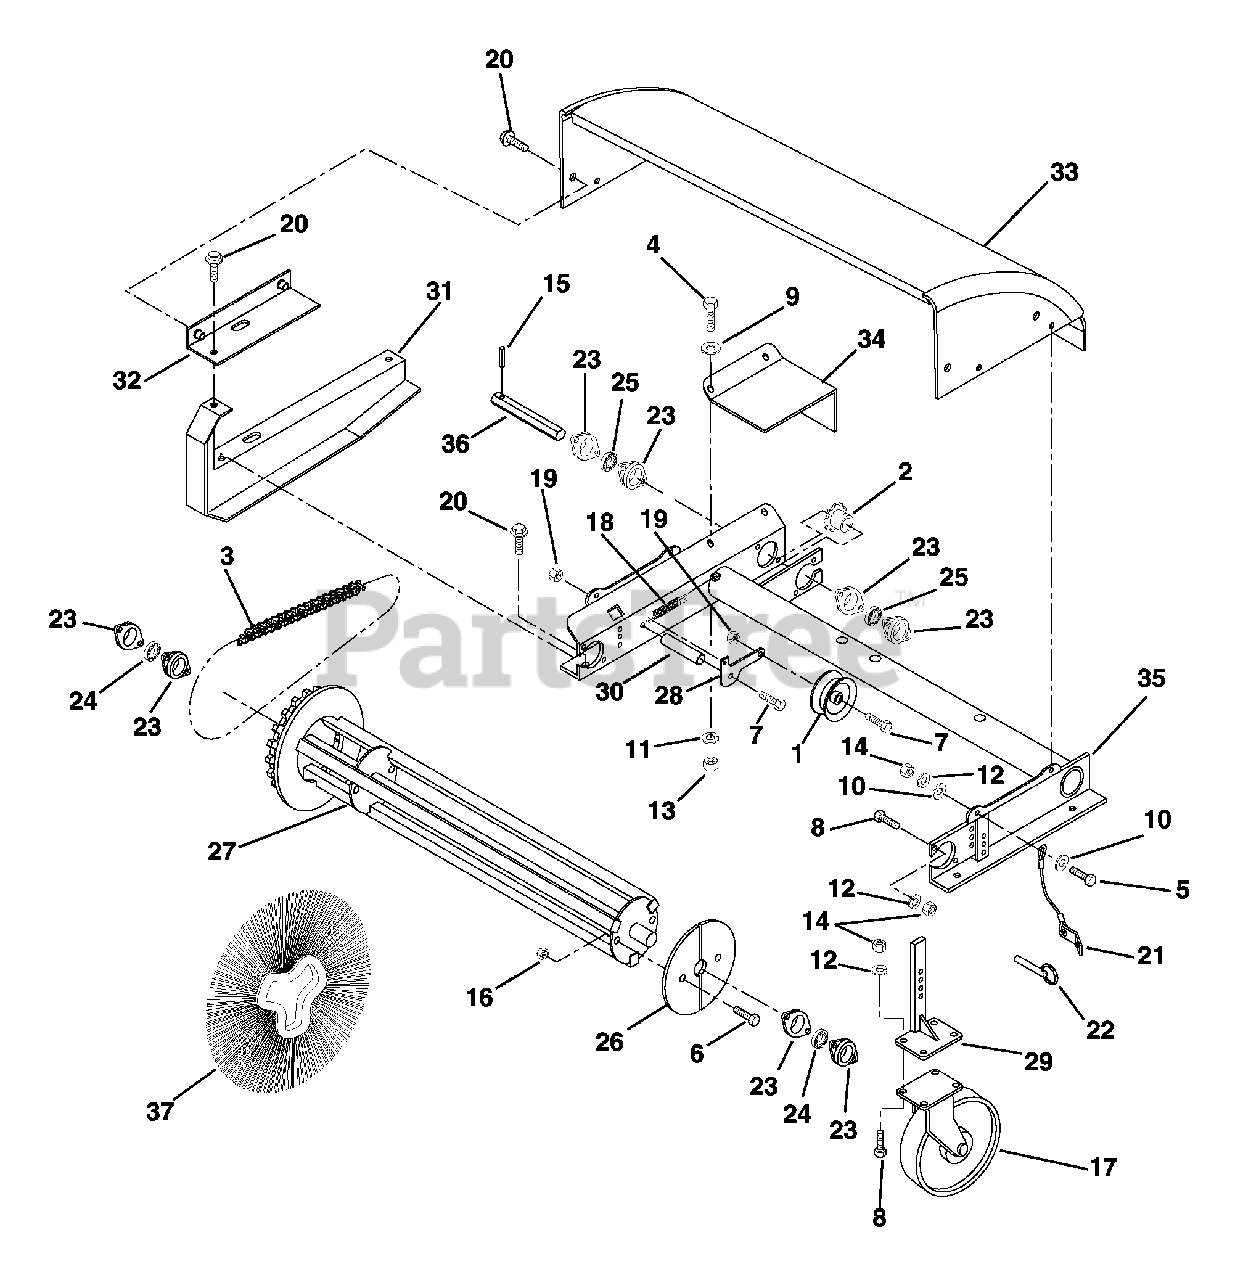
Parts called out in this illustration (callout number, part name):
1	Chain Tightener
2	Sprocket
3	Chain, Assembly #40 x 106
4	Bolt, Hex .25-20 x .75 Grade 5
5	Bolt, Hex .31-18 x 1.00 Grade 5
6	Bolt, Hex .31-18 x 2.25 Grade 5
7	Bolt, Hex .38-16 x 1.50 Grade 5
8	Bolt, Hex .31-18 x .75 Grade 5
9	Washer, Flat Steel .28 x .62 x .065
10	Washer, Flat Steel .31 x .73 x .065
11	Washer, Lock .25 x .062 Regular
12	Washer, Lock .31 x .078 Regular
13	Nut, Hex .25-20
14	Nut, Hex .31-18
15	Pin, Spring Lok .19 x 1.25
16	Nut, Lok Stamped .31-18
17	Wheel, 5 inch Diameter
18	Spring, Tension .50 x 3.00
19	Nut, Locking Center .38-16
20	Screw, Gear 10.9 M6 x 1-20
21	Lanyard .06 Cable 1.25 x 6
22	Pin, Hitch .38 x 2
23	Flange, Spherical 2 inch
24	Bearing 1.00 Bore, Spherical
25	Bearing, Ball .84 Hex x 52 MM x 1.07
26	Retainer Plate
27	Weldment, Core
28	Arm, Idler
29	Weldment, Caster Leg
30	Bushing .62 x 12 Gauge x .75
31	Shield, Chain
32	Shield Chain Top
33	Weldment, Head
34	Shield, Input
35	Weldment, Broom Frame
36	Shaft, Hex 20.5 with Hole
37	Set, 24 Section
